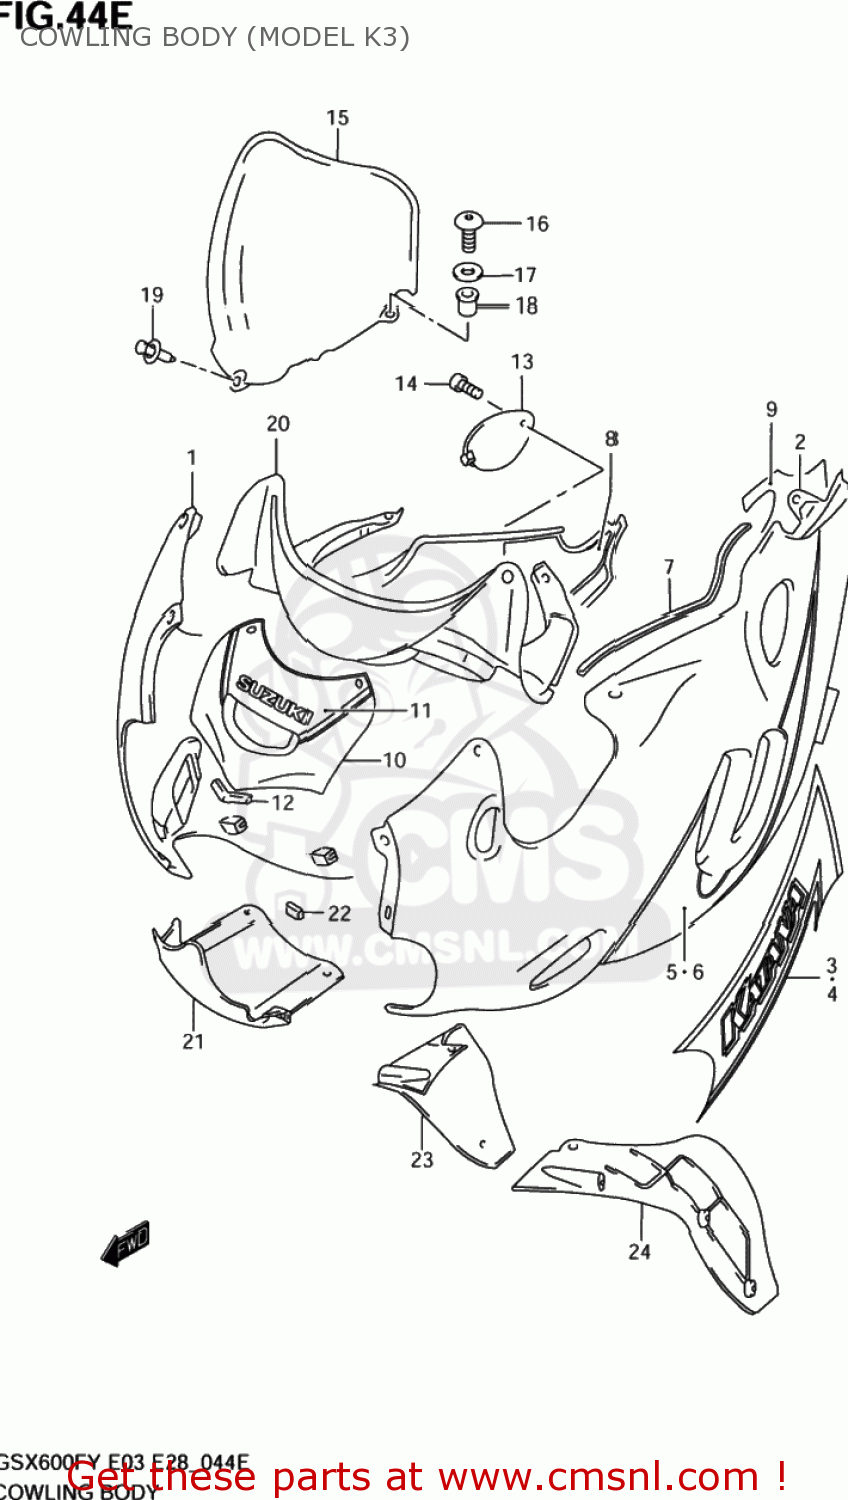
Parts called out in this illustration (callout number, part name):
1	COWLING ASSY,SIDE,R
2	COWLING ASSY,SIDE,L
3	TAPE,COWL UNDER MIDDLE,R
4	TAPE,COWL UNDER MIDDLE,L
5	TAPE SET,COWL UNDER LWR,R
6	TAPE SET,COWL UNDER LWR,L
7	MOLD,COWLING
8	SHIELD,COWLING COVER,R
9	SHIELD,COWLING COVER,L
10	PANEL,COWLING CTR UPR
11	TAPE,PANEL COWLING CTR UPR
12	CUSHION,CTR PANEL UPR
13	LID,OIL
14	SCREW(6X16)
15	WINDSCREEN
16	SCREW(5X14)
17	WASHER
18	NUT
19	CLIP(BLACK)
20	PANEL,METER
21	PANEL,COWLING CTR LWR
22	CUSHION,CENTER PANEL,LOWER
23	PANEL,COWLING INNER,R
24	PANEL,COWLING INNER,L
